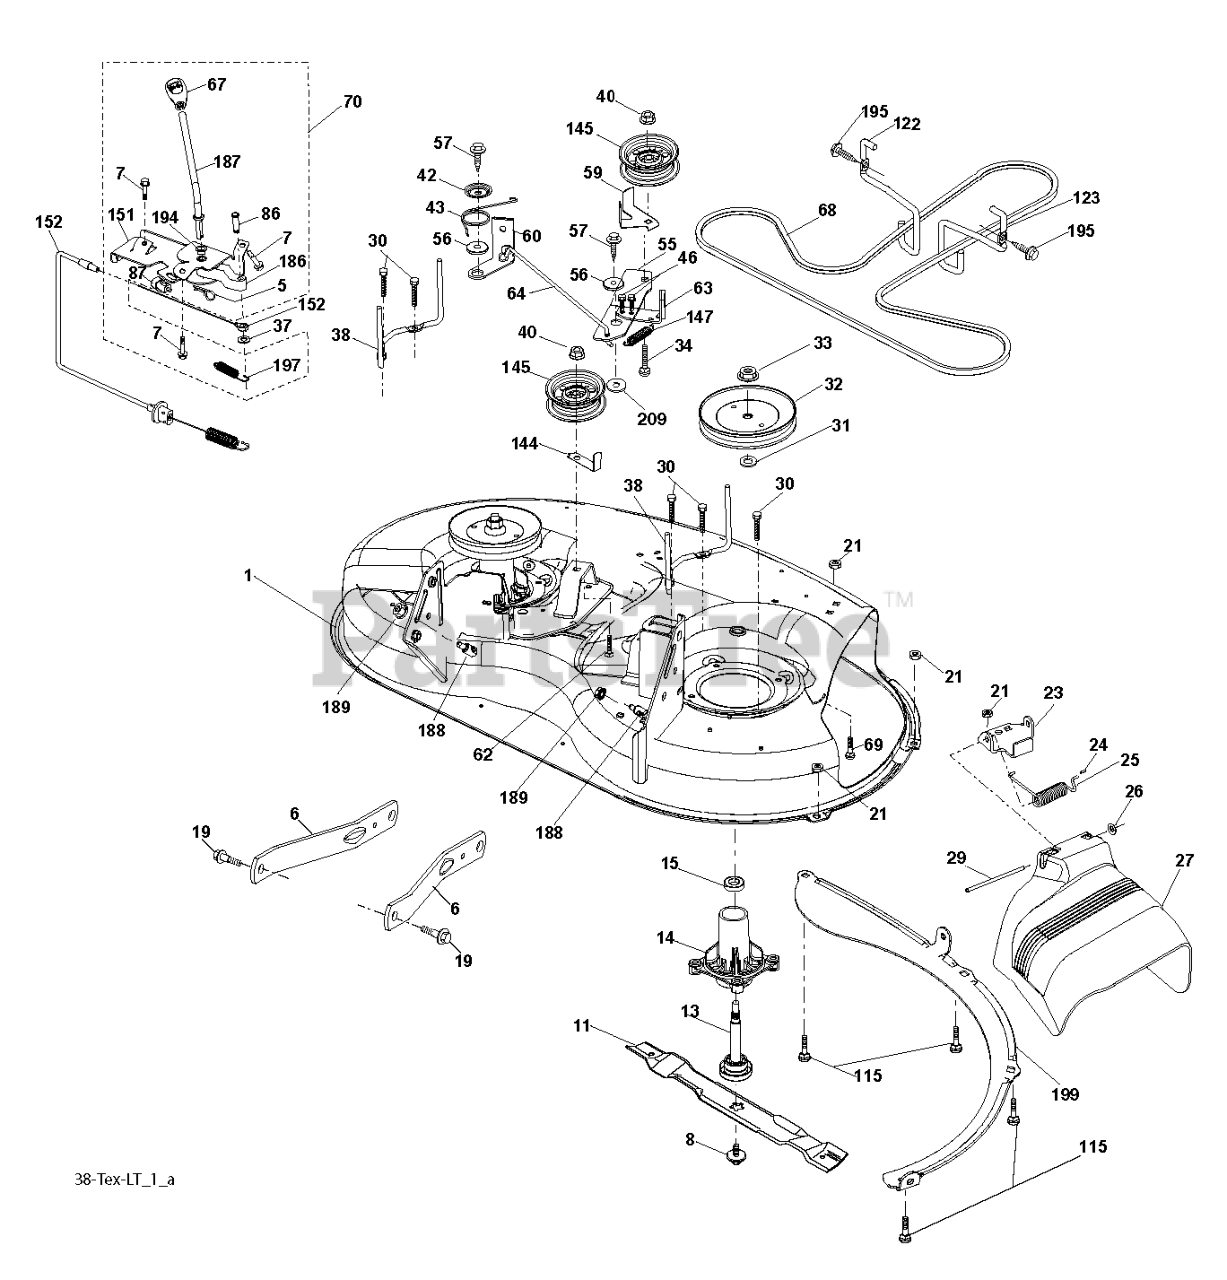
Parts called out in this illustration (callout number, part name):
1	HOUSING
5	RETAINER-SPRNG RB
6	ARM.SUSPENSION.MOWER.R
7	SCREW
8	BOLT.WASHER.ASM.7/16-2
11	BLADE 38" PREMIUM
14	RP.HOUSING.MANDREL.4PT.
19	BOLT.SHOULDER
21	LOCKNUT
23	BRKT.DEFLECTOR.38"2005+
24	CAP-SLEEVE LT
25	SPRING.TORSION.DEFLECT
26	NUT PUSH M
27	SHIELD.DEFLECTOR.MWR.38-7/97CM
29	ROD.HINGE
30	SCREW, WASHER HEAD
31	WASHER.SPACER.MANDREL
32	PULLEY.MANDREL.5.0.PD.38"
33	NUT.FLANGE.LOCK.TOP
34	BOLT.3/8-16X1.50
36	PULLEY.IDLER.48"PRIMARY
37	WASHER
38	KEEPER BELT LH MANDREL
40	NUT LOCK FLG 3/8-16 UNC
42	SPRING.TORSION.BRAKE
43	SRPING.TORSION.RETAINE
46	SCREW.1/4-20X5/8
56	SPACER.RETAINER
57	SCREW 3/8-16X1
59	GUARD, BELT
60	ARM BRAKE MOWER RH 38"
62	BOLT.3/8-16X1.50
63	RP ARM.BRAKE.MOWER.38"LH.TEX
64	LINK BRAKE
67	HANDLE.CLUTCH.CABLE.LT
69	BOLT
70	CLUTCH.ASM.MANUAL.LT.PRED
86	PIN ATTACHMENT CABLE
87	SWITCH.INTRLCK.CLUTCH.
122	KEEPER BELT ENGINE LH
123	KEEPER BELT RH
144	KEEPER, BELT IDLER
147	SPRING RETURN
151	BRACKET.CLUTCH CBL.PRED LT
152	CLUTCH CABLE
186	ARM ACTUATOR
187	LEVER.CONTROL.CL.CABLE.PRED LT
188	STUD.FASTNER.W/ANTI-ROTATE
189	NUT LOCK HEX FLANGE 5/16-18
194	BEARING.CONTROL.LEVER.CLUTCH
195	SCREW, 3/8-16X3/4
197	SPRING.PLUNGER.ACTUATOR
199	BAFFLE.VORTEX.FRONT.38"
209	WASHER 12/32X2X10GA
